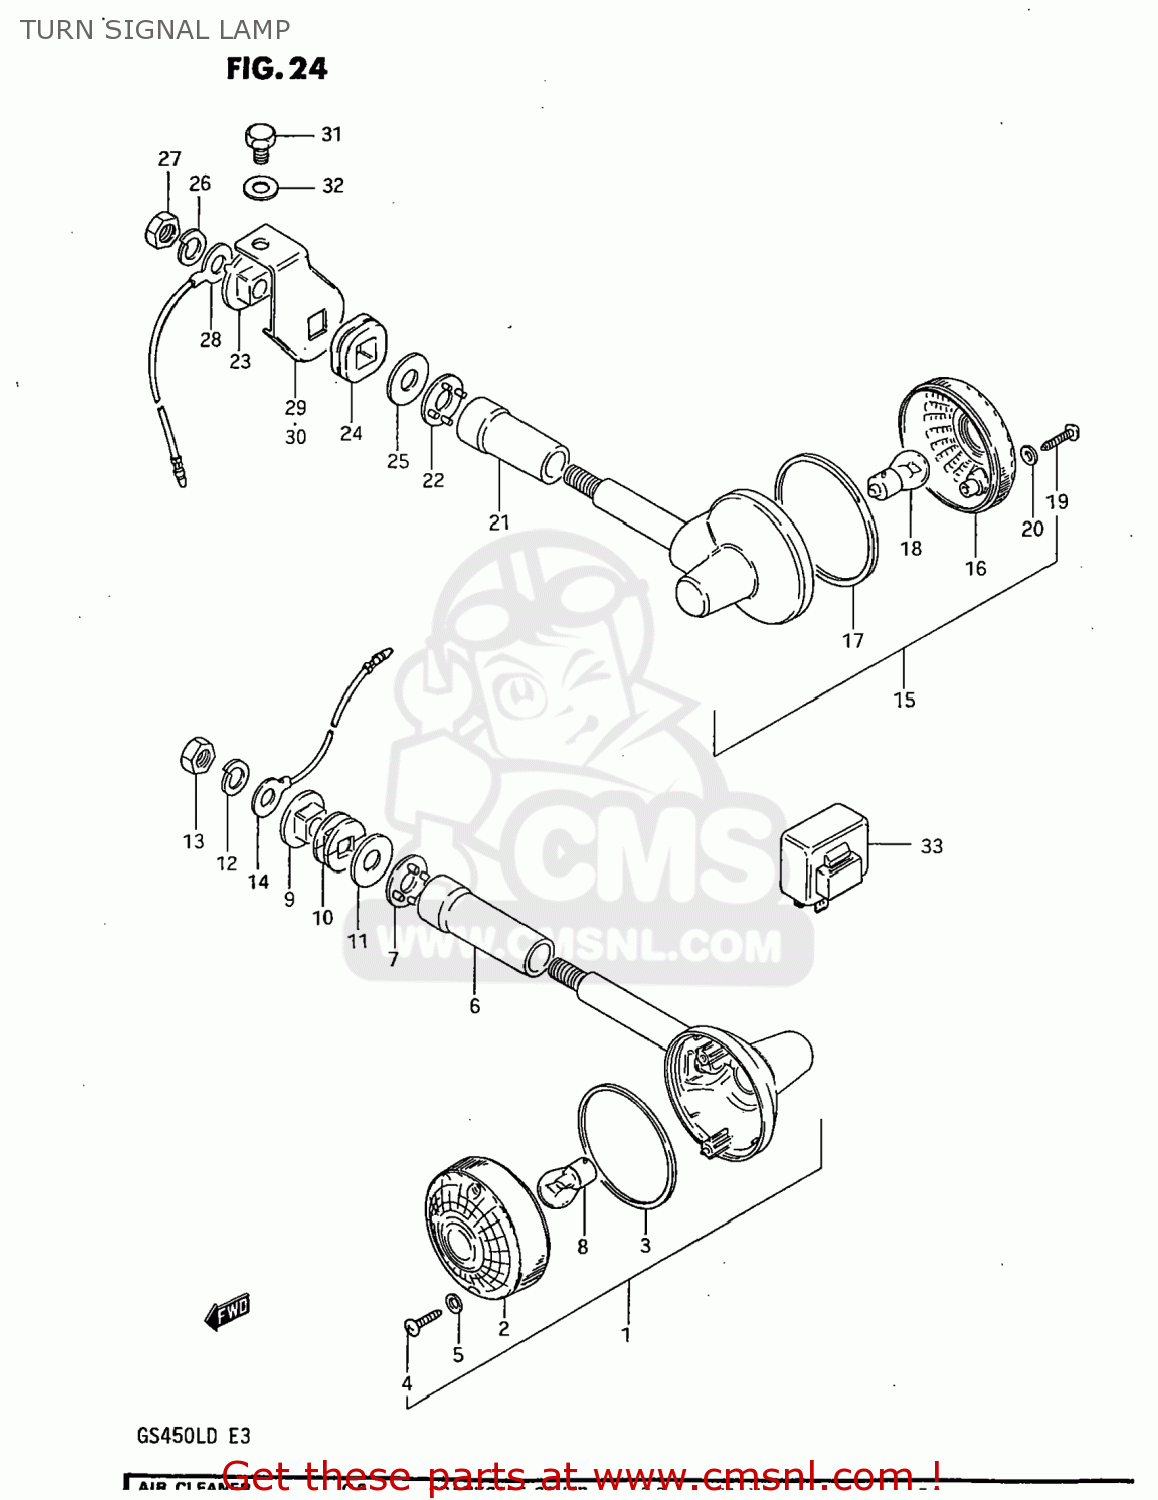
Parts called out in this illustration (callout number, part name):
1	LAMP ASSY,TURNSIGNAL
2	LENS
3	GASKET (NAS)
4	SCREW
5	GASKET (NAS)
6	COVER,STAY
7	SPACER
8	BULB(12V23W,STANLEY,A4577A)
9	SPACER
10	CUSHION
11	WASHER (10.5X30X2.3)
12	LOCK WASHER
13	NUT
14	LEAD WIRE,EARTH
15	LAMP ASSY,RR TURNSIGNAL
16	LENS
17	GASKET (NAS)
18	BULB(12V23W,STANLEY,A4577A)
19	SCREW
20	GASKET (NAS)
21	COVER
22	SPACER
23	SPACER
24	CUSHION
25	WASHER (10.5X30X2.3)
26	LOCK WASHER
27	NUT
28	LEAD WIRE,EARTH
29	BRACKET,RR TURNSIGNAL LAMP,R
30	BRACKET,REAR TURN SIGNAL
31	BOLT 8X12
32	WASHER
33	RELAY,TURN SIGNAL
